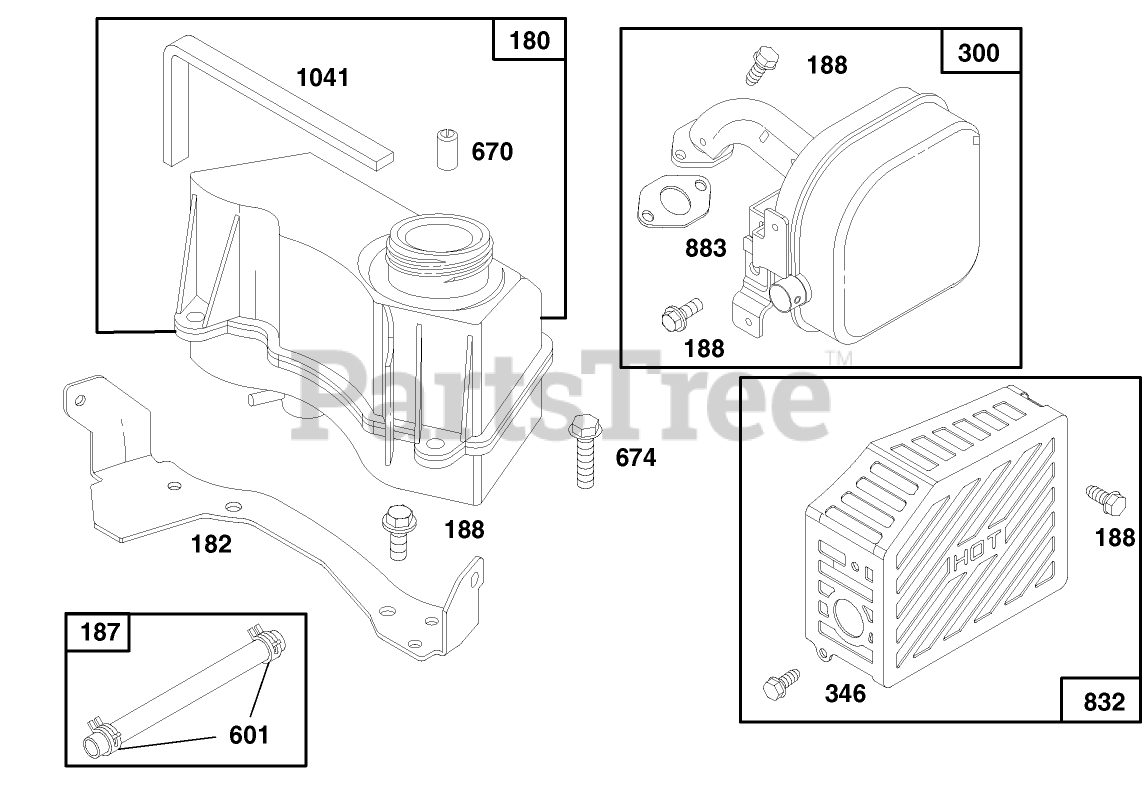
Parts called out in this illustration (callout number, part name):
180	TANK ASSY - FUEL
187	BRIGGS 296004
300	MUFFLER - EXHAUST
670	SPACER
674	SCREW - HEX HEAD
